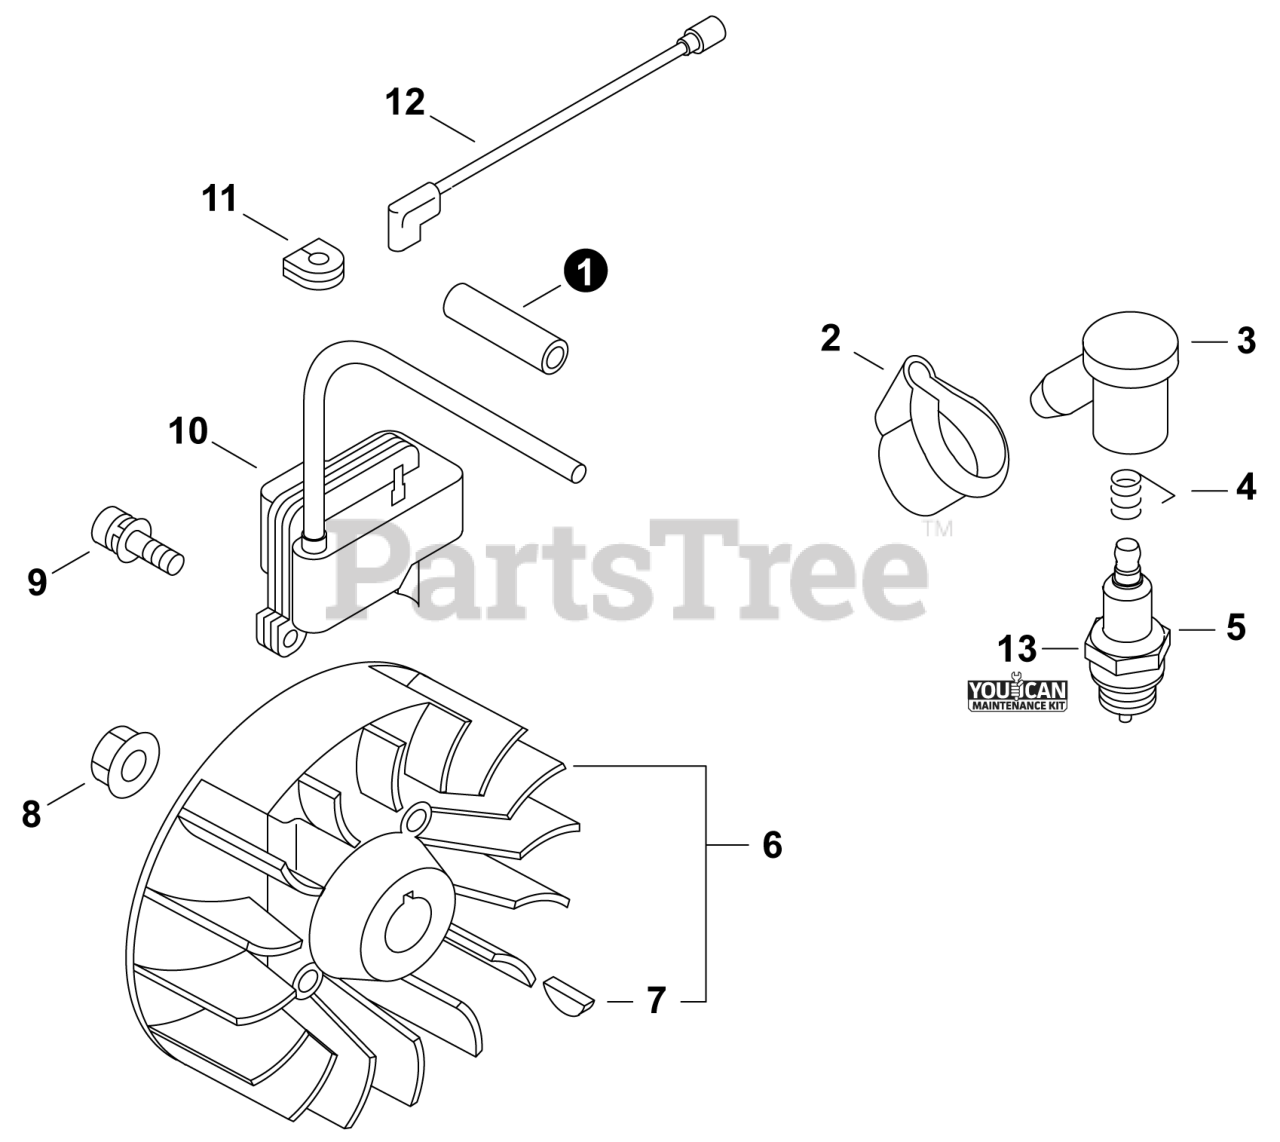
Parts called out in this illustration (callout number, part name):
1	TUBE, INSULATOR 7x8.6x55
2	COVER, DUST
3	CAP, SPARK PLUG
4	TERMINAL, SPARK PLUG
5	SPARK PLUG - BPM7A
6	FLYWHEEL KIT
7	KEY, WOODRUFF 3x14
8	NUT, FLANGE 10x1.25
9	BOLT 5x20
10	COIL, IGNITION
12	LEAD 170 MM
13	TUNE-UP KIT - YOUCAN?
